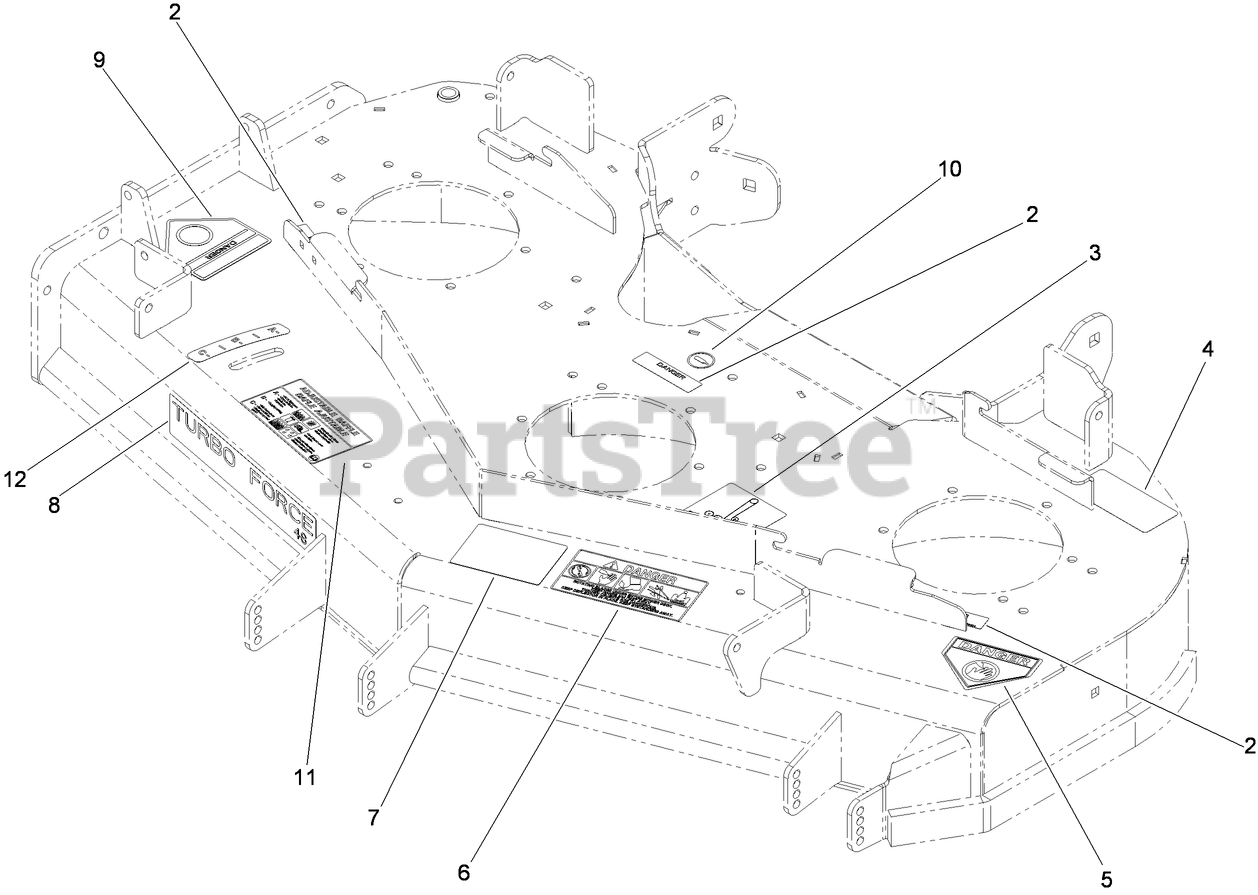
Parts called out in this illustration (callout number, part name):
2	DECAL-COVER, MISSING
3	DECAL-ROUTING, DECK BELT
4	DECAL-TORQUE
5	DECAL-DANGER
6	DECAL-DANGER, THROWN OBJECT
7	DECAL-SCALP, ANTI
9	DECAL-DANGER
10	DECAL-GREASE
11	DECAL-ADJUSTMENT, BAFFLE
12	DECAL-SETTING, BAFFLE
